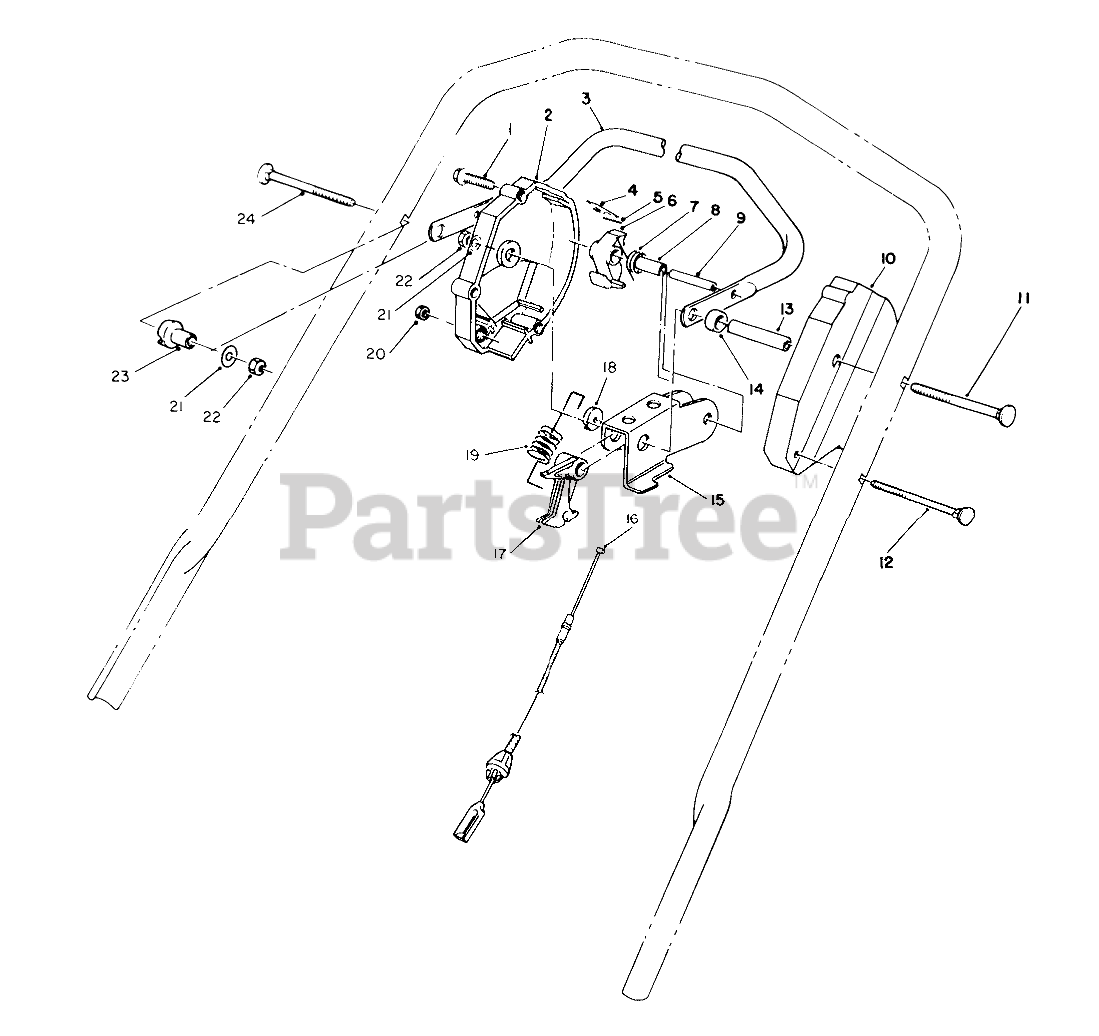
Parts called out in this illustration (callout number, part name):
1	SCREW-HWHTF
2	Housing-Control
3	Bar-Control
4	SPRING-LEAF
5	PIN-INSERT
6	HOOK-CONTROL
7	SPRING-TORSION
8	SPACER
9	PIN-ROLL, SLOTTED
10	HOUSING-CONTROL, LH
11	Screw-Handle
12	HANDLE SCREW
13	TUBING-SPACER
14	SPACER-NYLON
15	ROCKER
16	Cable-BBC
17	LEVER-CABLE
18	WASHER-NYLON
19	SPRING-DETENT
20	NUT-HEX
21	WASHER-PLAIN
22	NUT-LOCK, NI
23	SPACER-SUPPORT
24	SCREW-HANDLE
